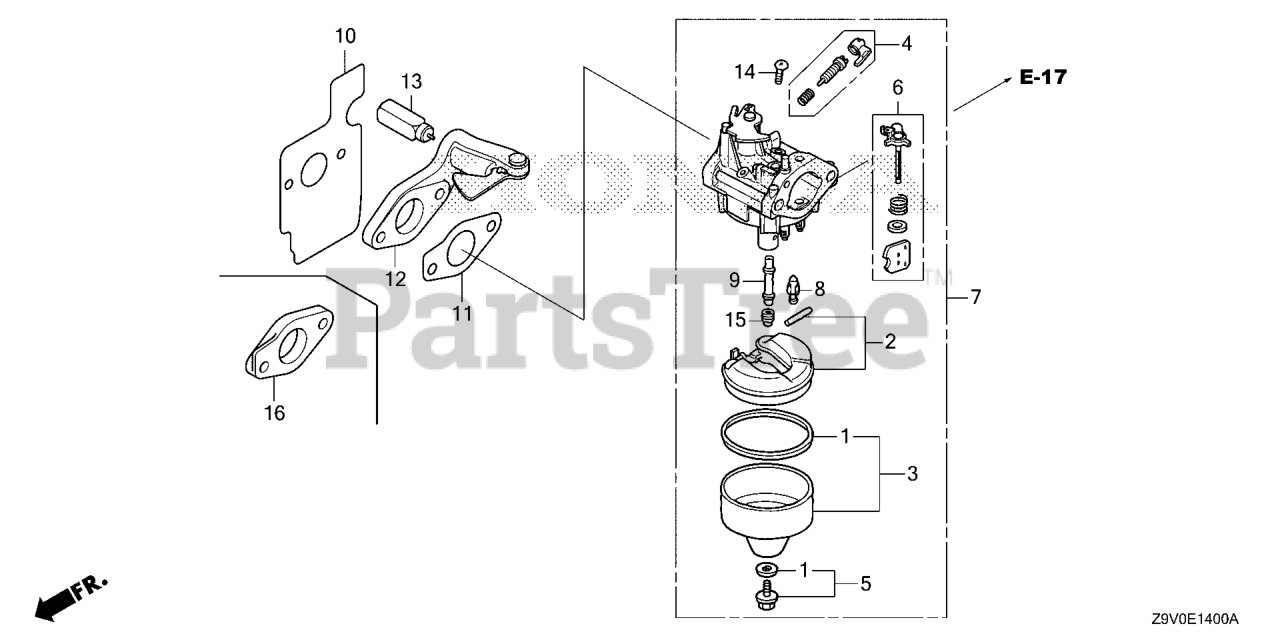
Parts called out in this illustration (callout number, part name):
1	GASKET SET
2	FLOAT SET
3	CHAMBER SET, FLOAT
4	SCREW SET (CARBURETOR NO.)
5	SCREW SET B
5	SCREW SET
7	CARBURETOR ASSY. (BB76J A)
8	VALVE, FLOAT (Honda Code 7934714). (CARBURETOR NO.)
9	NOZZLE, MAIN
10	GASKET, INSULATOR
11	GASKET, CARBURETOR
12	CONTROL ASSY., CHOKE
13	THERMO WAX ASSY.
14	SCREW, PAN (5X6)
15	JET, MAIN (#62) (Honda Code 0635482). (CARBURETOR NO.)
15	JET, MAIN (#65) Use up to Engine SN BB30A D.
15	JET, MAIN (#68) Use up to Engine SN BB30A D.
